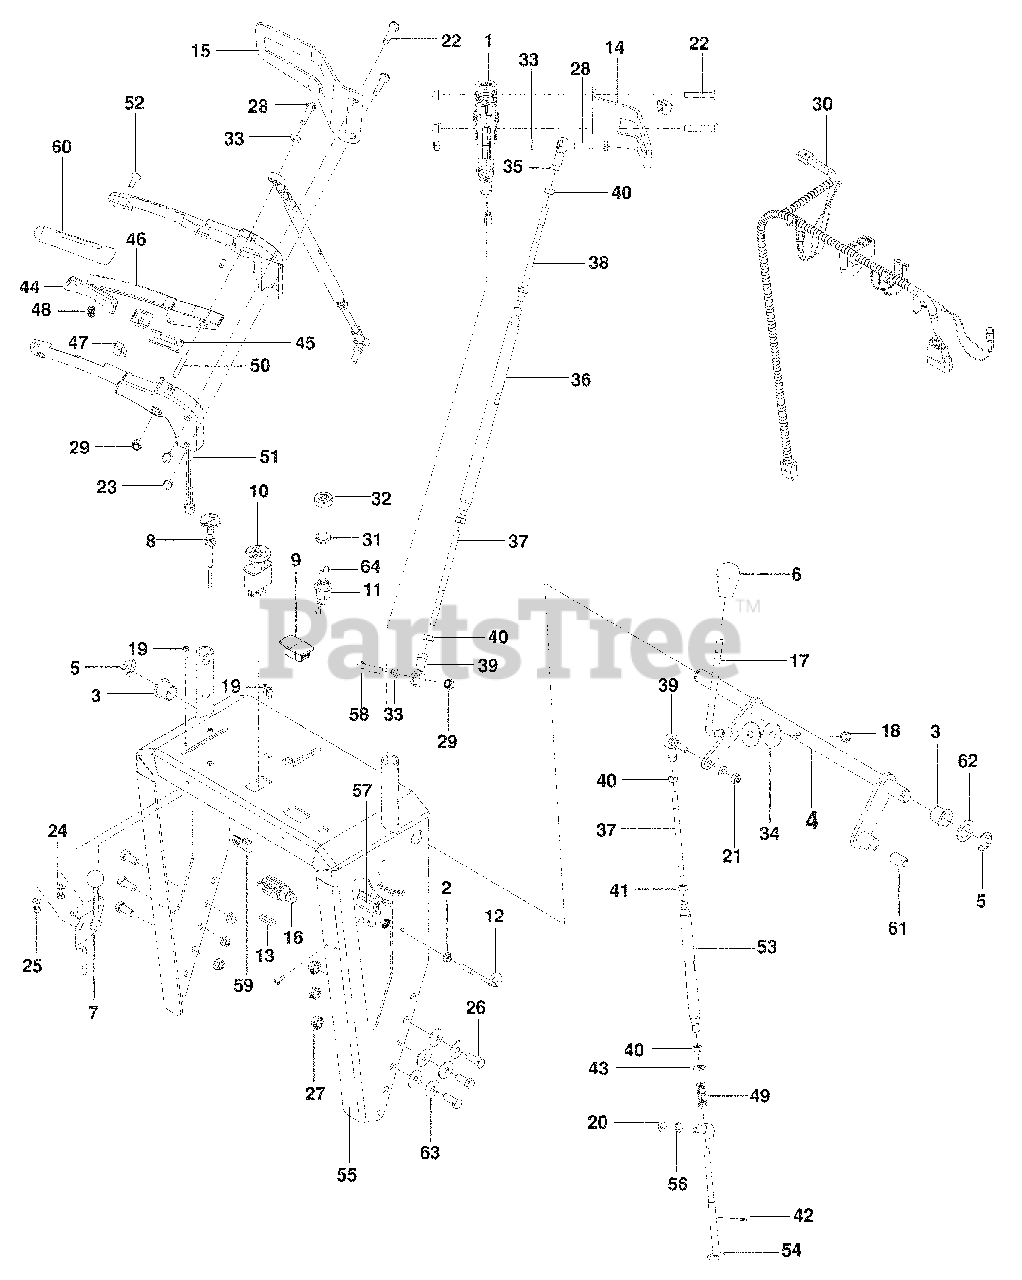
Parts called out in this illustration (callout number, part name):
2	NUT 5/16-18 HEX WHIZLK
3	BEARING, FLANGE
4	SPEED CONTROL
5	E RING, 20MM
6	KNOB, SHIFT
7	CONTROL, THROTTLE
8	CONTROL, CHOKE
9	PLUG, DASH, SVC MINDER
10	SWITCH, CLUTCH
11	SWITCH, IGNITION w/KEY
12	GUIDE, ROPE
13	PLATE, NUT
14	GUARD, HAND RH
15	GUARD, HAND LH
17	ROD, SHIFT
18	NUT 3/8-16 HEX JAM NYLOC
19	SCREW #10-24 x ½ HEX
20	WASHER 3/8 SAE FLAT
21	NUT M8 x 1.25 NYLOC
22	SCREW, PAN HD 5/16-18 x 1¾
23	NUT, ACORN 5/16-18
24	WASHER #10 FLAT
25	NUT #10-24 HEX NYLOC
26	HCS 3/8-16 x 7/8
27	NUT 3/8-16 HEX WHIZLK NYL
28	HCS 5/16-18 x 1¾
29	NUT 5/16-18 HEX NYLOC
30	HARNESS, UPPER HANDLE
31	NUT, IGNITION SWITCH
32	CAP, IGNITION SWITCH NUT
33	WASHER 5/16 SLW
34	WASHER, CONE
35	ROD END 8 MM, RH
36	TUBE, ADJUSTING
39	ROD END 8 MM
40	NUT .8MM x 1.25 HEX
41	NUT .8MM x 1.25 LH
42	ROLL PIN 3 MM
43	WASHER, 10 MM
44	ACTUATOR, OPC
45	LOCK, NEUTRAL
50	PIN, GROOVE 7MM x 38MM
51	HARNESS, SWITCH
52	SCREW, OVAL HEAD 6MM
53	TUBE, ADJUSTING
54	ROD, HEADED
55	UPPER HANDLE w/DECAL
56	E-RING, 10MM
58	HCS 5/16-18 x 1¼
60	GRIP, FOAM
63	WASHER, SPRING
64	KEY, IGNITION
